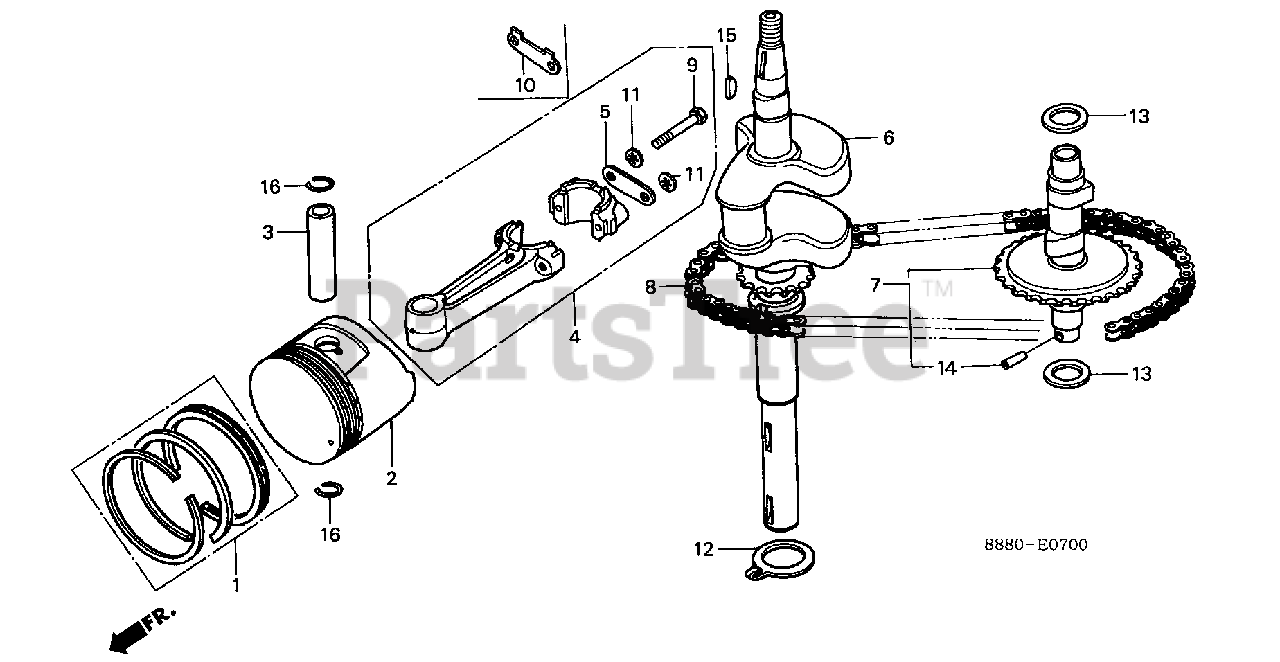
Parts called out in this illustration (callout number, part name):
1	RING SET, PISTON (STD)
1	RING SET, PISTON (0.25)
1	RING SET, PISTON (0.50)
1	RING SET, PISTON (0.75)
2	PISTON (STD)
2	PISTON (0.25)
2	PISTON (0.50)
2	PISTON (0.75)
3	PIN, PISTON
4	ROD ASSY., CONNECTING
5	WASHER A, CONNECTING ROD
5	WASHER, CONNECTING ROD
6	CRANKSHAFT (N2)
7	CAMSHAFT ASSY.
8	CHAIN, CAM (NOT AVAILABLE)
9	BOLT, CONNECTING ROD (6MM)
9	BOLT, CONNECTING ROD (6MM) (NOT AVAILABLE)
9	BOLT, CONNECTING ROD (7MM)
10	WASHER B, CONNECTING ROD
11	WASHER, LOCK (6MM) (N/A: SEE ASSEMBLY)
11	WASHER, LOCK (7MM)
12	WASHER, THRUST (35MM) (NOT AVAILABLE)
13	WASHER, THRUST (18MM)
14	PIN, SPRING (2.5X16)
15	KEY, WOODRUFF (25X18)
16	CLIP, PISTON PIN (15MM)
